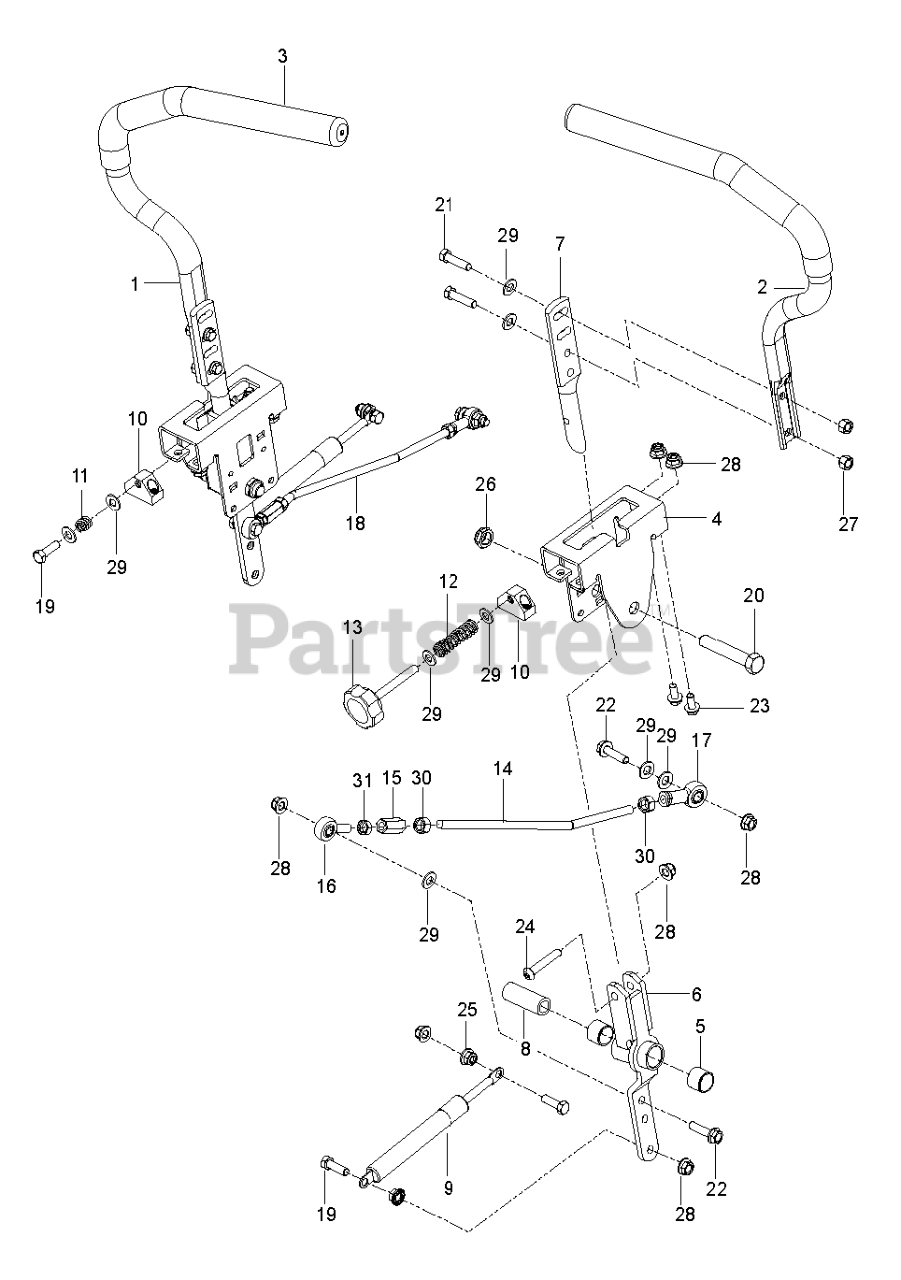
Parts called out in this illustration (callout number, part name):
1	TUBE.LEVER.CONTROL.ZTR.RT.428
2	TUBE.LEVER.CONTROL.ZTR.LT.428
3	GRIP - DRIVE LEVER 12"
4	BRACKET.CONTROLS.ZTR.X431
5	BEARING
6	CONTROL.WELDMENT.RZ
7	LEVER.HANDLE MOUNT
8	SPACER.PIVOT.CONTROL
10	BLOCK TRACKING CONTROL ZTR
12	SPRING COMPRESSION 2.0
14	ROD, CONTROL
15	ROD END COUPLER
16	ROD.END.MALE.LH.THREAD
17	JOINT.HEIM.FEML.5/16.RH.THREAD
18	BOLT.5/16-18X1-1/4 FULL.THREAD
19	HCS 1/2-13 X 2-3/4 GD 5 ZD
20	CAPSCREW 5/16 X 1/1/2 HEX HEAD
21	HHFS 5/16-18 X 1.25 TPBLT GD 5
22	HHFS 5/16-18 X 3/4
23	SCREW 5/16-18 X 1 3/4 BTN-HD
24	NUT 5/16C WHIZ
25	NUT 1/2-13 HEX JM NYL
26	NUT 5/16 NYLOC
27	5/16-18 NYLOC FLANGE NUT
28	WASHER
29	WASHER
31	NUT 5/16F LEFTHAND
